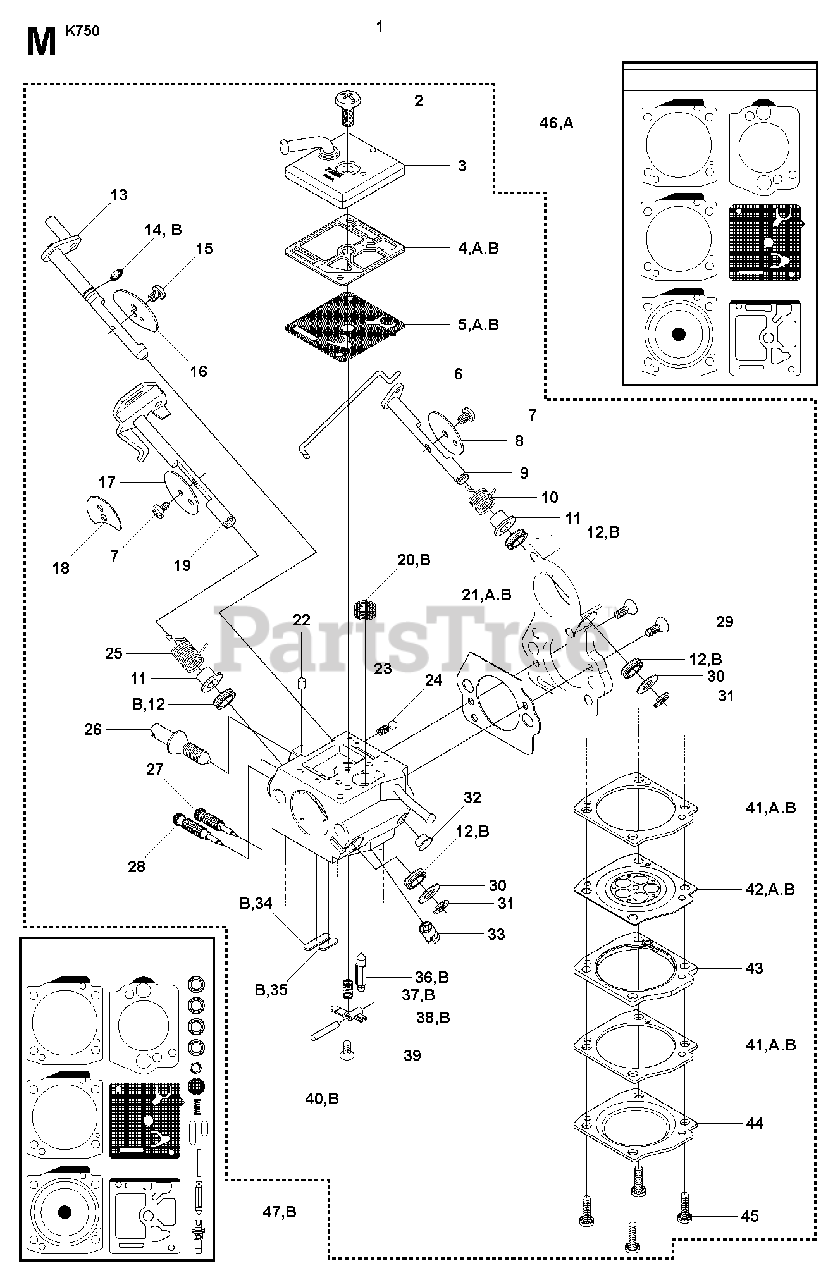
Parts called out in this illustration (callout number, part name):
1	CARBURETTORZama C3-EL29, Incl. 2 - 43
1	CARBURETTORZama C3-EL43, Incl. 2 - 43
5	DIAPHRAGM PUMP
18	CHOKE VALVEJapan only
40	PIN RETAINING SCREW
42	DIAPHRAGM ASSY
46	GASKET KITIncl. 4, 5, 21, 41, 42
47	GASKET KITIncl. 4, 5, 12, 14, 20, 21, 34-38, 40-42
